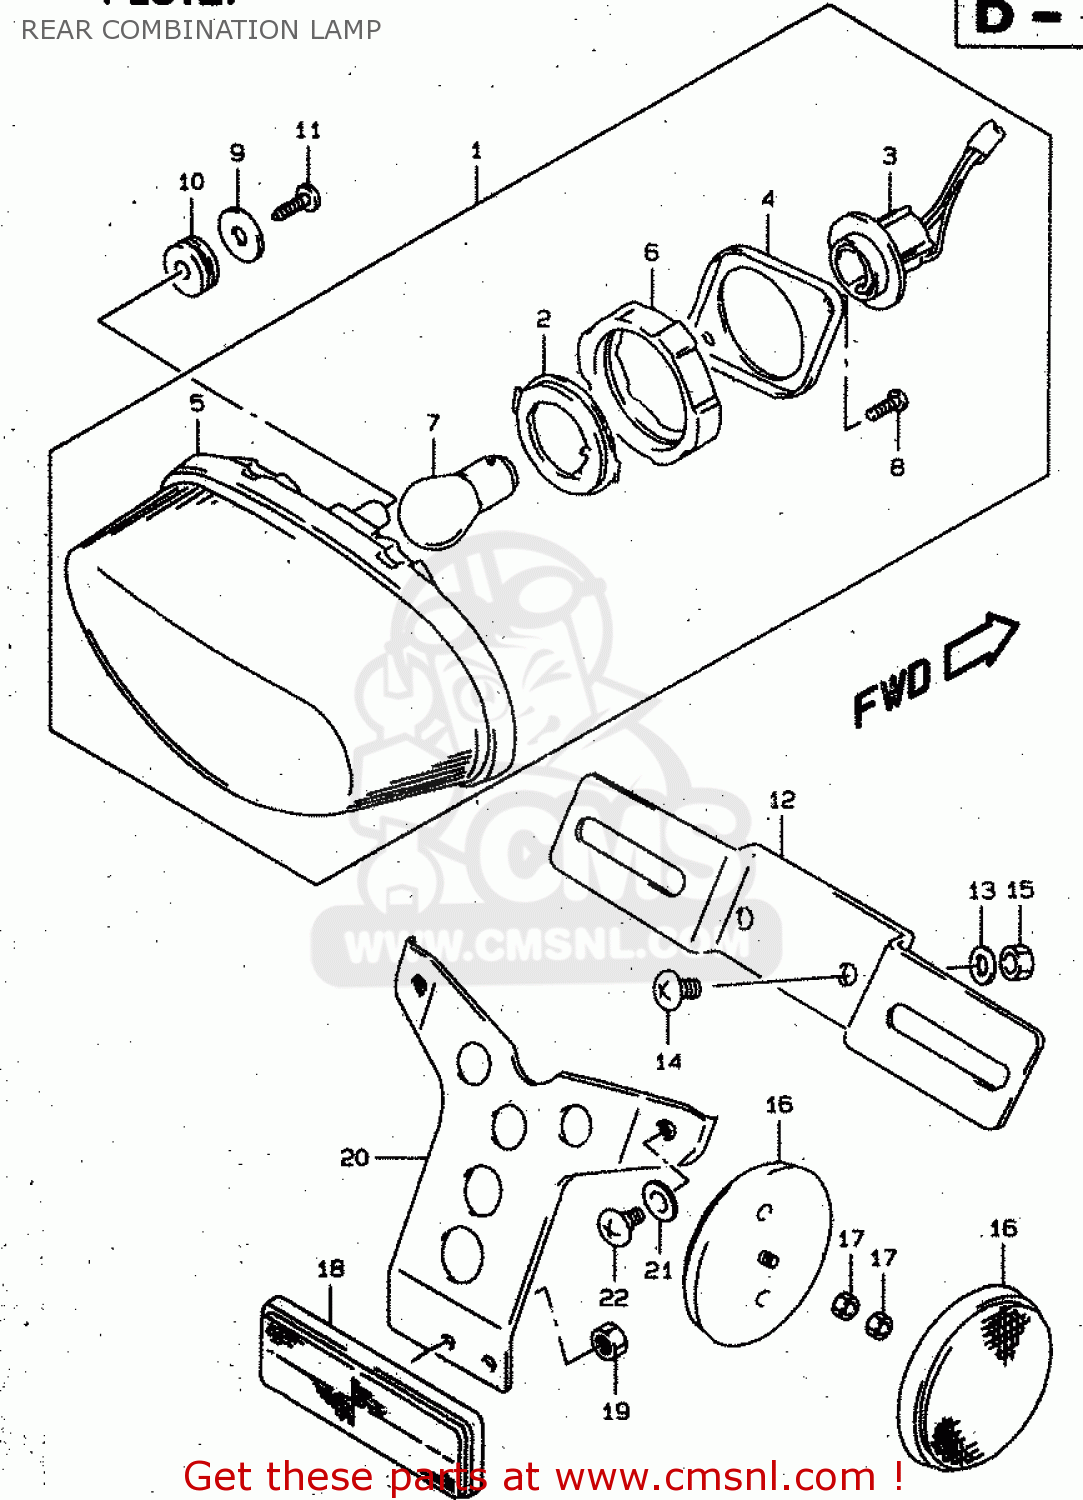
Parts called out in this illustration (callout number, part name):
1	LAMP ASSY,REAR
2	PLATE NO.1
3	SOCKET & CORD
4	PLATE NO.2
5	LAMP UNIT
6	CUSHION
7	BULB(12V21/5W)
8	SCREW
9	WASHER(5.5X20X1.2)
10	CUSHION
11	SCREW
12	BRACKET,LICENSE PLATE
13	WASHER(6.5X20X1.6)
14	SCREW 6X12
15	NUT 6MM
16	REFLECTOR,REFLEX
17	NUT
18	REFLECTOR ASSY,RR
19	NUT
20	BRACKET,RR REFLECTOR
21	WASHER(8.5X18X1.6)
22	SCREW (6X14)
